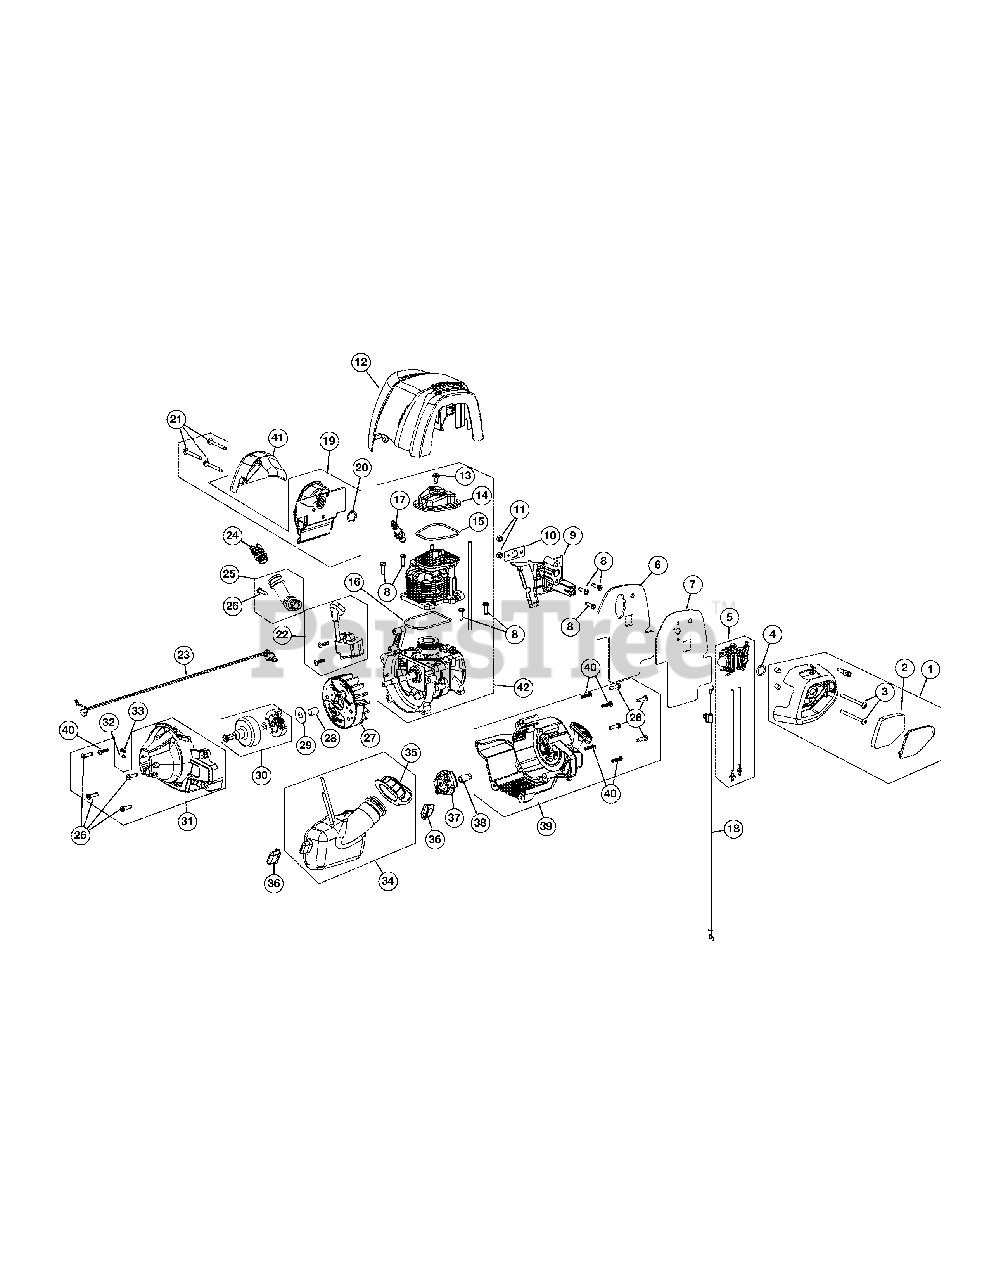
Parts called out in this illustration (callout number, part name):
1	Aircleaner Assembly (includes 2 & 3)
2	Air Filter
4	Carburetor O-Ring
5	Carburetor Assembly
6	Heat Shield
7	Carburetor Baffle
8	Screw
9	Insulator
10	Insulator Gasket
12	Engine Cover
14	Valve Cover
15	Valve O-Ring
16	Cylinder O-Ring
17	Spark Plug
18	Throttle Cable
19	Muffler Assembly (includes 20 & 21)
20	Muffler Gasket
21	Muffler Bolt
22	Module Assembly
23	Lead Wires
24	Oil Plug Assembly
25	Oil Fill Tube Assembly (includes 26)
26	Cover Screw
27	Flywheel
28	Spacer
29	Clutch Washer
30	Clutch Assembly
31	Clutch Cover Assembly (includes 26 & 40)
32	Anti-rotation Screw
33	Clamp Screw & Nut
34	Fuel Tank (includes 36)
35	Fuel Cap
36	Fuel Tank Pad
37	Pawl Assembly
38	Electric Start Adapter
39	Starter Cover Assembly (includes 26 & 40)
40	Starter Screw
41	Muffler Shield
42	Short Block Assembly
